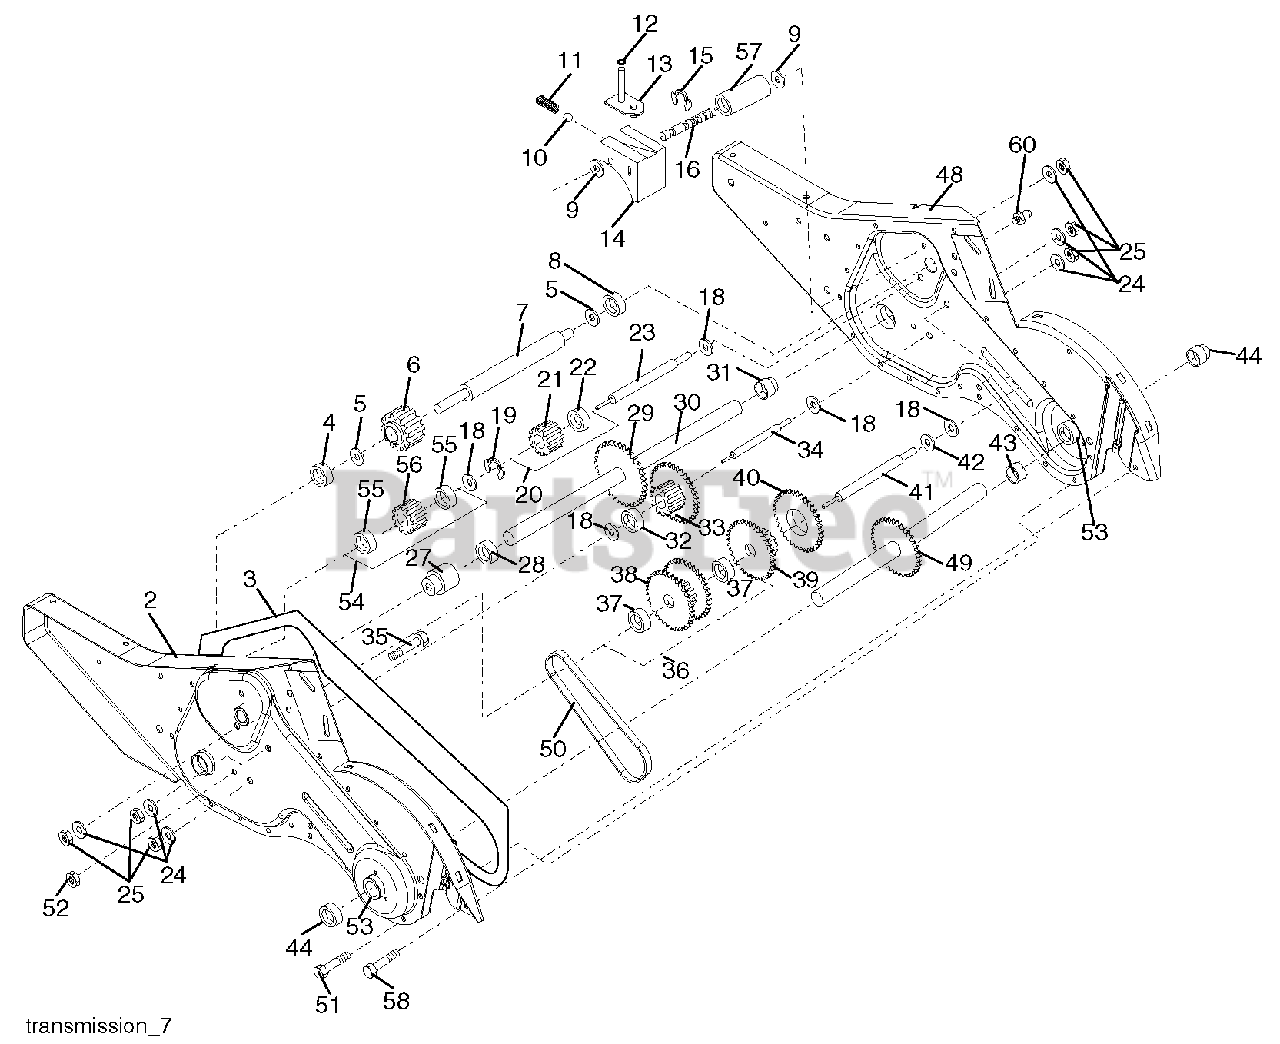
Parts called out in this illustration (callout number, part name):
1	Transmission Assembly
2	Gearcase, L.H. w/Bearing
3	Gasket, Gearcase
4	Bearing, Needle
5	Washer, Thrust 5/8 x 1.10 x 1/32
6	Pinion, Input
7	Shaft, In put
8	Bearing, Needle
9	Washer, Seal
10	Ball, Steel
11	Spring, Shift, Fork
12	O-Ring
13	Arm, Shift
14	Fork, Shift
15	Ring, Klip
16	Shaft, Shift
18	Washer
19	Ring, Klip
20	Gear, As sem bly, Reverse Idler
21	Gear, Re verse Idler
22	Bearing, Needle
23	Shaft, Re verse Idler
24	Washer, Lock 7/16
25	Nut, Hex 7/16-20
27	Bearing, Shaft, Ground Drive L.H.
28	Spacer 0.765 x 1.125 x 1.23
29	Chain #35-50 Pitch
30	Ground Shaft Assembly
31	Bearing, Shaft, Ground Drive R.H.
32	Spacer 0.70 x 1.00 x 1.150
33	Sprocket and Gear Assembly
34	Shaft, Re duc tion (2nd)
35	Screw, Whiz, Lock 5/16-18 x 3-1/2
36	Sprocket Assembly w/Bearing
37	Bearing, Needle
38	Sprocket, Tine
39	Gear, Clus ter, Red 1st & 2nd
40	Gear, Re verse
41	Shaft, Re duc tion (1st)
42	Washer, Thrust
43	Spacer 1.01 x 1.75 x 0.760
44	Seal Asm. OIl
48	Gearcase, R.H. w/Bearing
49	Shaft, Tine
50	Chain, Roller #50-50 Pitch
51	Screw 1/4-20 x 1/2
52	Nut, Hex 5/16-18
53	Bearing Kit, Tine Shaft
54	Gear, DRT Idler w/Bearing
55	Bearing, Needle
56	Gear, DRT Idler
57	Spacer, Split .52 x .64 x 1.04
58	Screw 1/4-20 x .875
60	Fitting Grease
60	Grease, Plastilube #1
